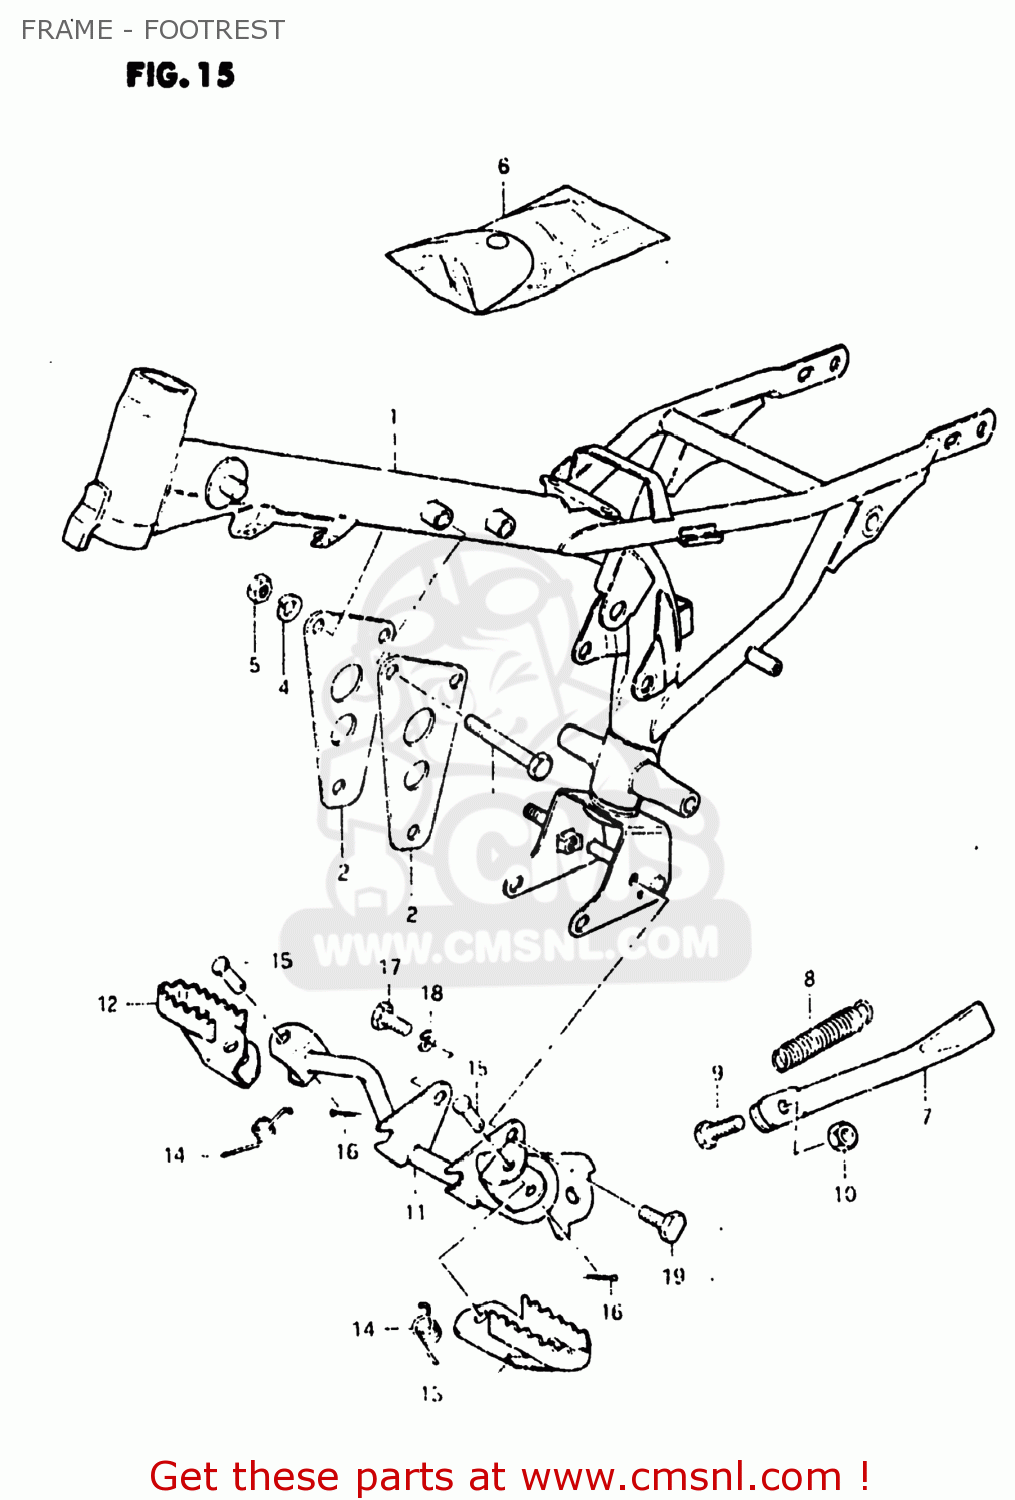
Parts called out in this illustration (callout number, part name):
1	FRAME
2	PLATE,ENG MTG
3	BOLT
4	LOCK WASHER
5	NUT
6	TOOL SET
7	STAND,SIDE
8	SPRING
9	BOLT 8X22
10	NUT
11	BAR,FR FOOTREST
12	FOOTREST,FRONT,RIGHT
13	FOOTREST
14	SPRING
15	PIN
16	PIN 20X20
17	BOLT
18	LOCK WASHER
19	BOLT(8X14)
